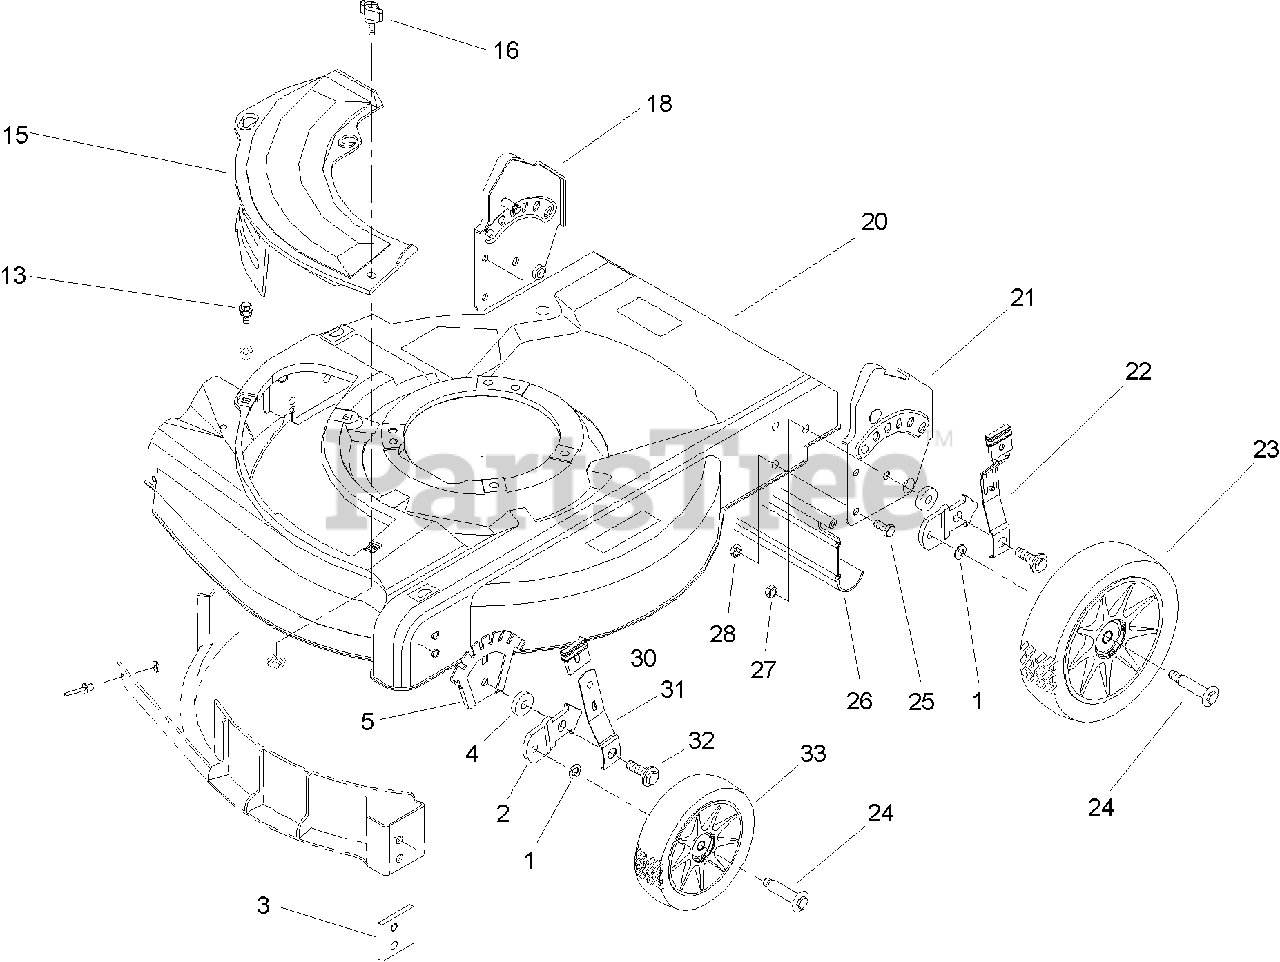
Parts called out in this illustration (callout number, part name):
2	BRACKET-HEIGHT ADJUSTMENT, WHEEL
3	PLATE-BAFFLE
4	WASHER-WHEEL
5	PLATE-HEIGHT, ADJUSTMENT
13	SCREW-SEMS
15	PLATE-MULCH
18	RH HANDLE BRACKET ASM
20	HOUSING ASM
21	LH HANDLE BRACKET ASM
22	REAR SPRING ARM ASM
23	WHEEL AND TIRE ASM
24	BOLT-SHOULDER
25	SCREW-HH
26	SHIELD-TRAILING
27	NUT-LOCK, NI
28	NUT-LOCK, NI
30	KNOB-LEVER, HEIGHT ADJUSTMENT
31	ARM-FRONT SPRING
32	BOLT-SHOULDER
33	WHEEL AND TIRE ASM
